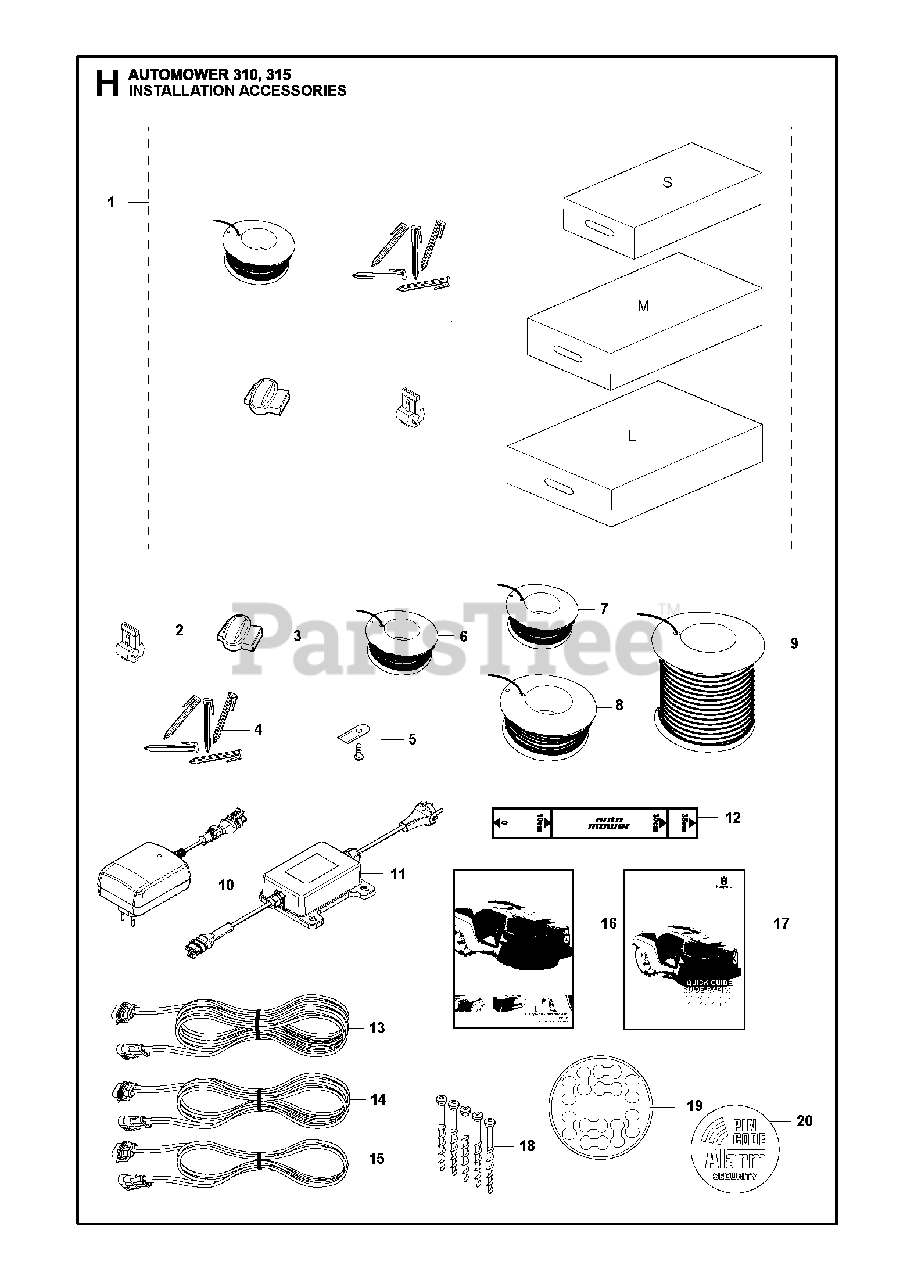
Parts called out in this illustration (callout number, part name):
1	SMALL AUTOMOWER INSTA
1	Automower Install, Medium
1	LARGE AUTOMOWER INSTA
2	BRAKER
2	Connector, 5 Pcs Blist
3	SPLICE KIT
3	Splicer Coupler, 5 Pcs
3	Splicer Coupler, 100 P
4	Staples, 100-Pack
5	Blade Set, 9 Piece
5	Blade Set, 45 Piece
5	Blade Set, 300 Piece
6	WIRE 50M STANDARD �2.7MM,BLIST
6	WIRE BOUNDARY 150M
6	WIRE 150M BLISTER
7	WIRE 250M
8	Wire, 500M
9	Wire, 800M
11	POWER UNIT US
12	RULER / CENTIMETERS
13	Cable Assembly, Low Voltage
14	Cable Assembly, Low Voltage
15	Cable Assembly, Low Voltage
18	SCREW KIT ANCHOR SCREW 5 PCS
19	STICKER CABLE MARKERS KIT 10PC
20	LABEL SECURITY
